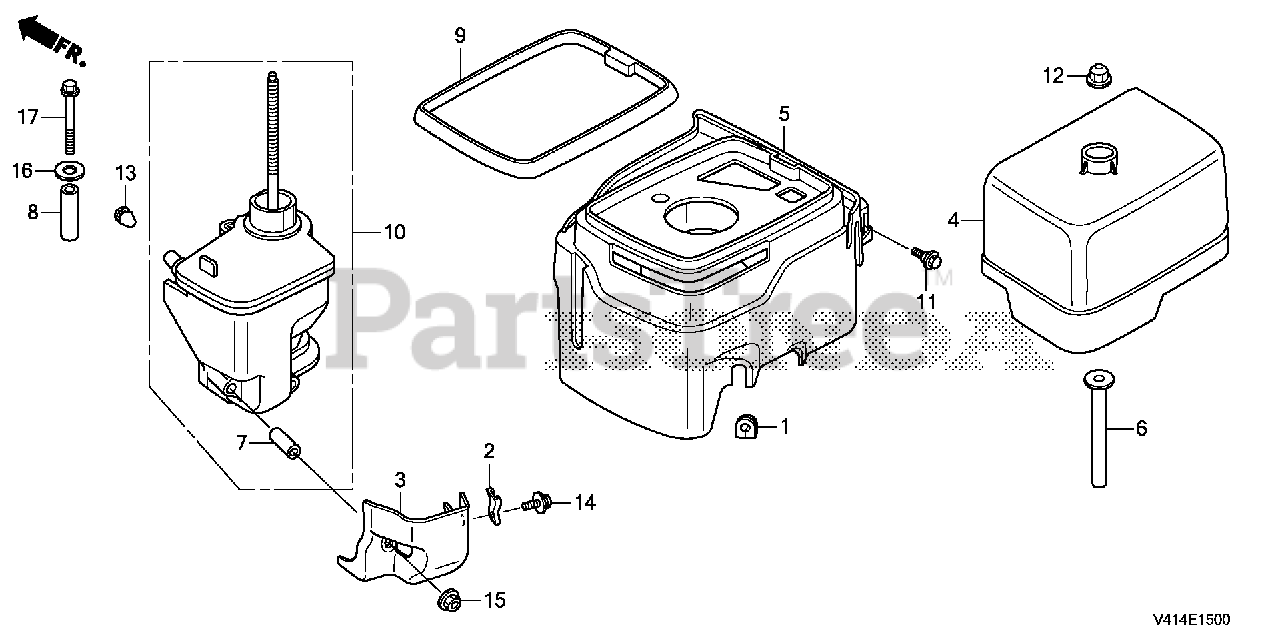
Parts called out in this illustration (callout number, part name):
1	GROMMET, OIL PIPE HOLDER
2	HOLDER, CONTROL CABLE
3	STAY, WIRE HOLDER
4	COVER, AIR CLEANER HOUSING
5	NOSE, MUFFLER
6	COLLAR A, AIR CLEANER
7	COLLAR, AIR CLEANER
8	COLLAR B, AIR CLEANER
9	SEAL, AIR CLEANER
10	ELBOW, AIR CLEANER
11	BOLT, FLANGE (6MM)
12	NUT, FLANGE (6MM)
13	PLUG, CONE TYPE
14	SCREW-WASHER (5X10)
15	NUT, FLANGE (6MM)
16	WASHER, PLAIN (6MM)
17	BOLT, FLANGE (6X55)
